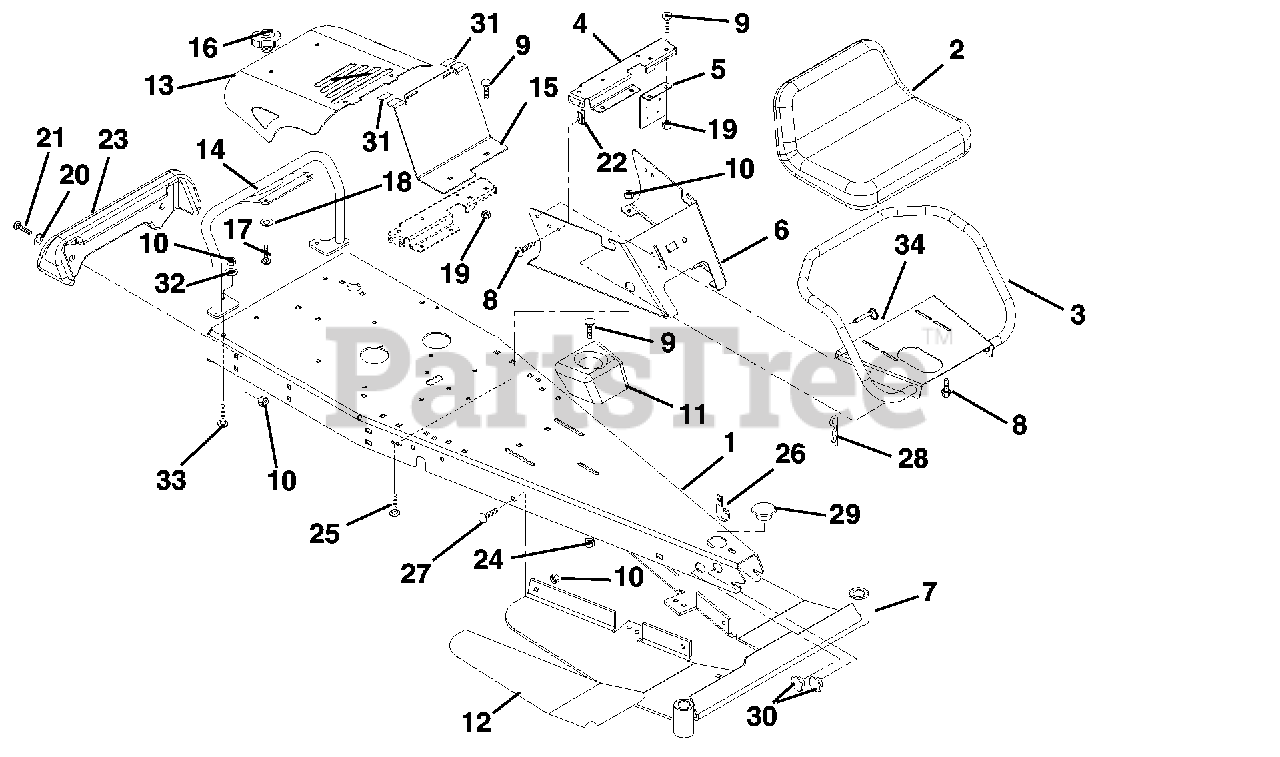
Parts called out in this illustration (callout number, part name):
1	FRAME,RER/SPORT-ZOOM
2	SEAT-LOW BACK TS2300
3	WLDMT, SEAT PLATE & ARMREST
4	REINFORCEMENT, SEAT SUPPORT
5	PANEL-SOLENOID MOUNTING
6	SEAT SUPPORT RER/MINI-Z-
7	WLDMT-FOOTREST RER/MINI-Z-
8	BLT-SERHFWH .31-18 X 1 YWZC
9	BLT-RDHDSQNK .31-18X.75 G5BZ
10	NUT-LK-TOP-FLG .38-16 BLKZC
11	CUP HOLDER RER
12	GRIP, RER FOOTREST (LH)
12	GRIP, RER FOOTREST (RH)
13	ENGINE-HOOD ARIENS
14	WLDM'T TUBE
15	BRACKET-HOOD SUPPORT
16	KNOB-CLAMPING, .312-18 NYLOC
17	@BLT-RHDSSQNK .31-18X.75 G5YZ
18	NUT-PUSH .312
19	NUT-LK-TOP-FLG .31-18 BLKZC
20	@WSHR-FL-STL.438X1.00X.083 YWZ
21	@BLT-HEX .38-16X1.75 GR5 YWZC
22	NUT-RTNR .25-20X.56
23	WEIGHT, SPORT-Z
24	@NUT-SPNLK-FLG .312-18 YWZC
25	BLT-RDHDSQNK .38-16X.75 G5BZ
26	J-CLAMP
27	BLT-RDHDSQNK .38-16X1.00 G5BZ
28	PIN-HAIR-EXT .12X.31X2.37 YWZC
29	HOLE PLUG, 1.38
30	HOLE PLUG 1.00"
31	TAPE-FOAM .12X1.00 VINYL
32	RETAINER, .38 PUSH-ON
33	@BLT-RDHDSHSQNK.38-16X1.0 G5YZ
34	PIN-DET W/RING .25X1.00
